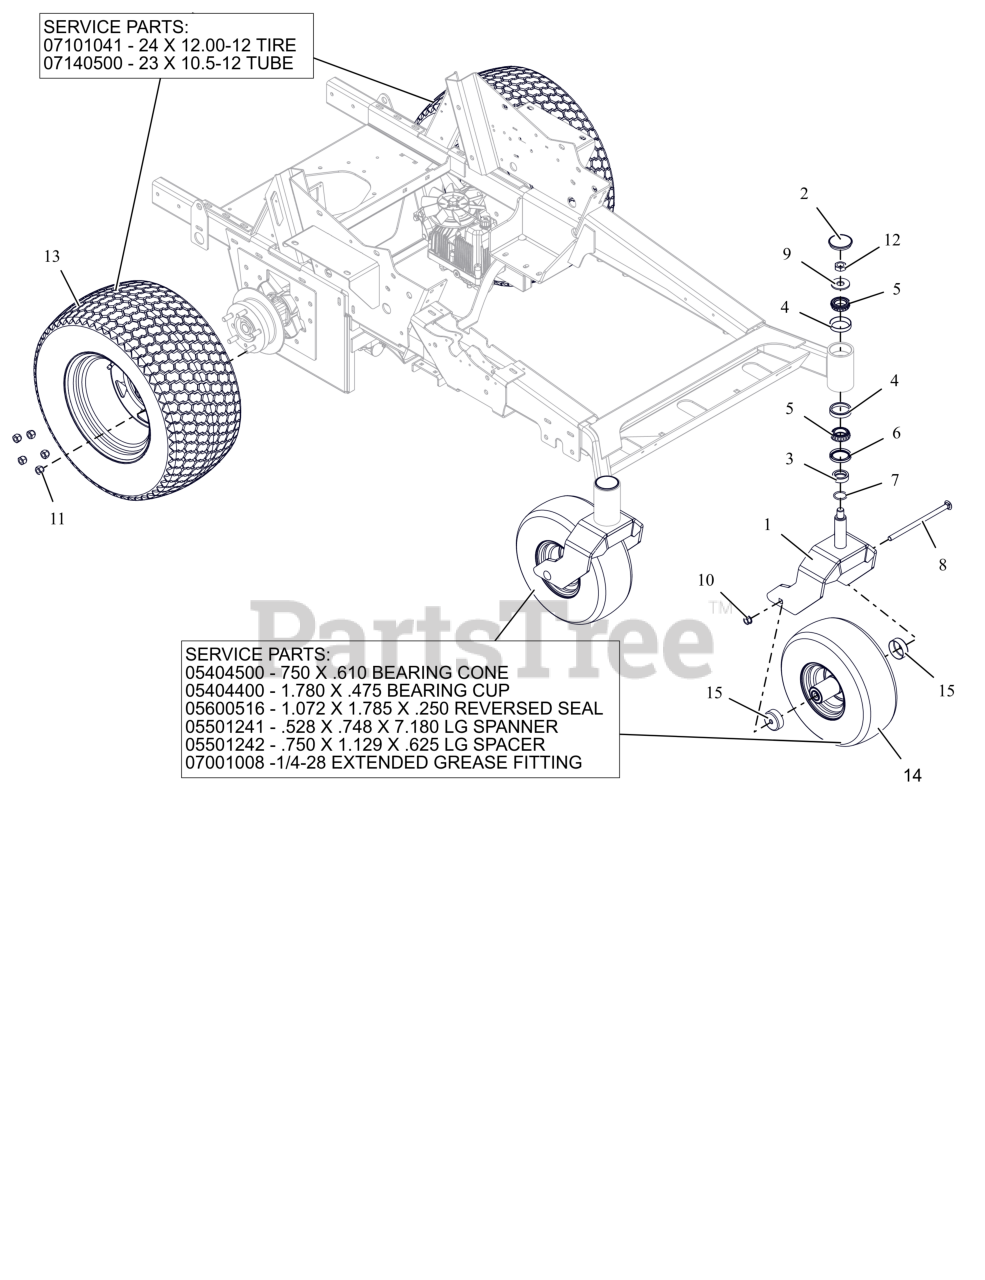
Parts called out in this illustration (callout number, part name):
1	WLDMT, CASTER FORK (RED)
2	CAP, DUST
3	SPCR, FRONT CASTER FORK
4	BRG-CUP 2.328X.465
5	BRG-CONE 1.25X.66
6	SEAL, OIL 1.75 X 2.332 X .312
8	BLT-RHSN .50-13X9.00 G5 ZCC NS
9	WSHR-FL-STL 0.812X2X0.148 ZCC
10	NUT-LK-CTR-FLG .500-13 GG ZCC
11	NUT, WHEEL .50-20 ZCC
12	NUT, JAM-TOPLOCK .750-16 ZCC
13	ASM-WHL/TIRE24X12.0-12 BLK RIM
13	TIRE, 24 X 12.00-12
13	TUBE 22,23&24X8.50/9.50/10.00/10.50/12.00-12
14	ASM, TIRE/WHEEL 15 X 6.00-6 SEMI
14	BRG-CONE .750X.61
14	BRG-CUP 1.781X.475
14	SEAL,1.072X1.785X.250 REVERSED
14	SPANNER, .528X.748X7.18 LG
14	SPACER, .750X1.129X.625 LG
14	GREASE FITTING 1/4-28 EXTENDED
15	SHIELD, WHEEL BEARING
